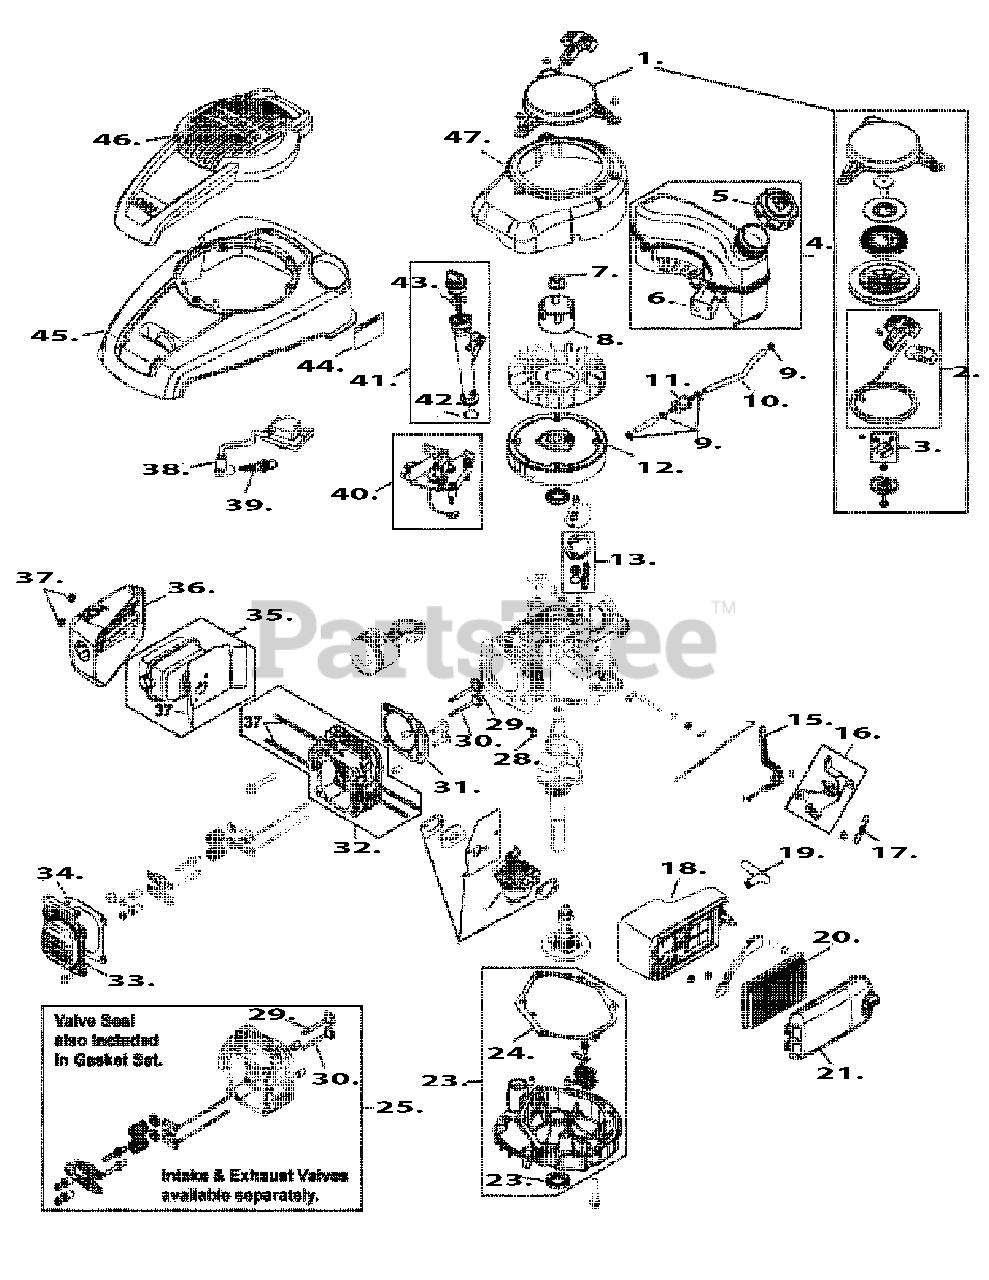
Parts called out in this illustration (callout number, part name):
1	STARTER, RECOIL
2	KIT, STARTER ROPE W/ HANDLE
3	KIT, PAWL REPAIR
4	KIT, FUEL TANK
6	BRACKET, FUEL TANK (LOWER)
9	CLAMP, FUEL LINE
10	LINE, FUEL
12	FLYWHEEL (ALUMINUM)
13	KIT, BREATHER FILTER
16	BRACKET, CONTROL
17	SPRING, GOVERNOR
18	KIT, AIR CLEANER BASE
19	TUBE, BREATHER
20	ELEMENT, AIR CLEANER
21	COVER, AIR CLEANER
22	KIT, OIL PAN
25	KIT, VALVE TRAIN
26	KIT, CARB GASKET
27	KIT, CARBURETOR (CHOKE) W/ GASKETS
31	KIT, HEAD GASKET
32	KIT, CYLINDER HEAD
33	KIT, VALVE COVER
34	GASKET, VALVE COVER
35	KIT, MUFFLER
37	KIT, EXHAUST HDW.
38	MODULE, IGNITION
39	PLUG, SPARK
40	KIT, FLYWHEEL BRAKE
41	KIT, DIPSTICK AND TUBE
42	O-RING, OIL FILL TUBE
43	O-RING, DIPSTICK
45	COVER, ENGINE (GRAY)
46	INSERT, ENGINE COVER
